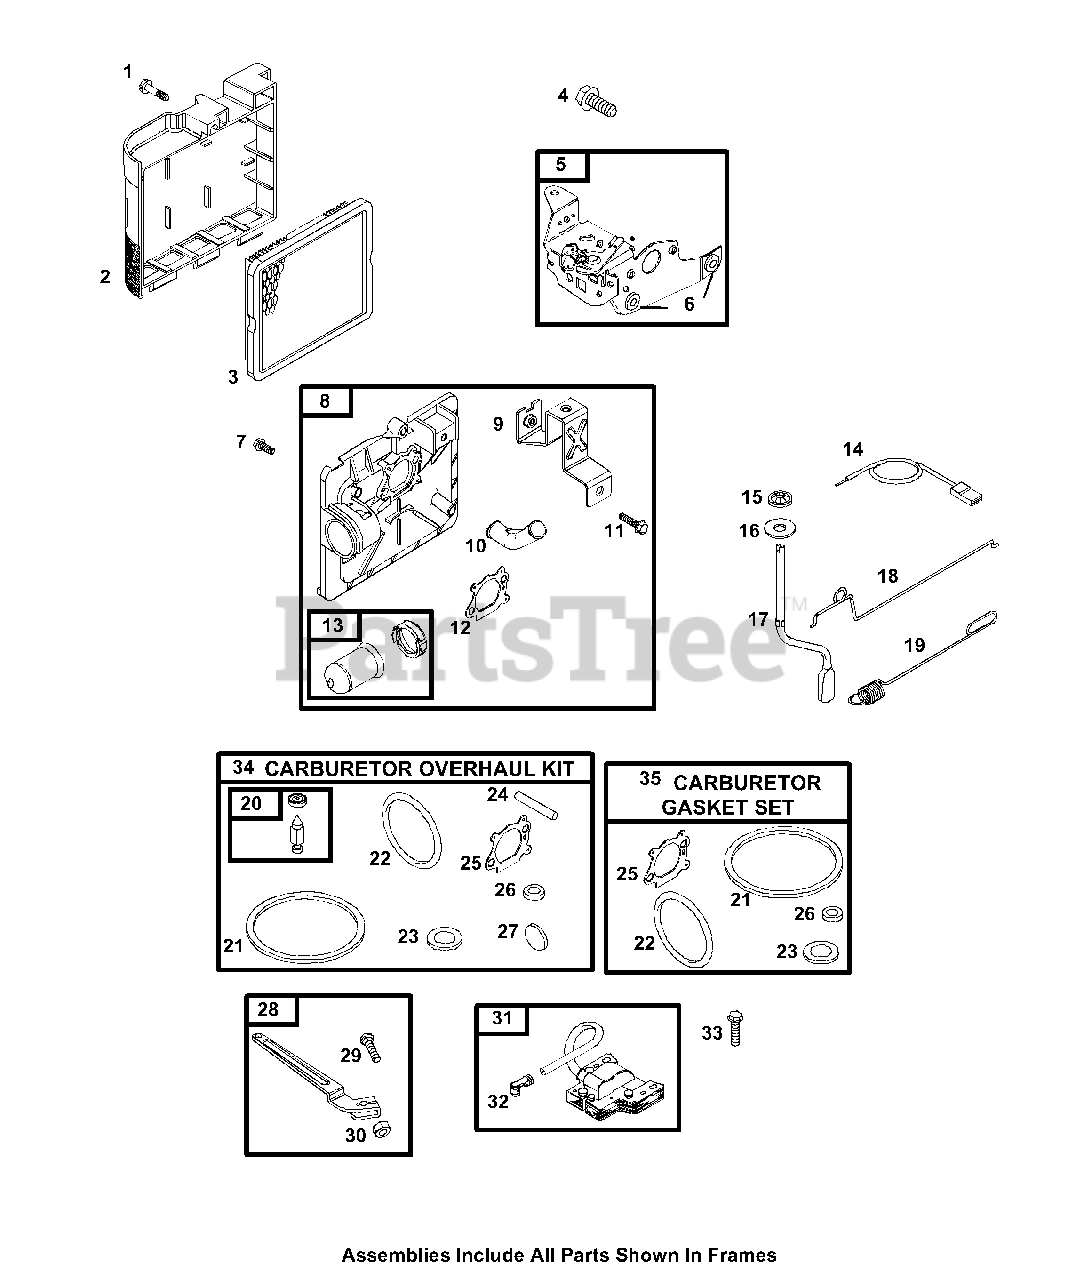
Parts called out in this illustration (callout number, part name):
1	Screw (Air Cleaner Cover)
2	Air Cleaner Cover
3	A/C Cartridge Filter
4	Screw (Control Bracket)
5	Control Bracket
6	Spacer
7	Screw (A/C Primer Base)
8	A/C Primer Base
9	Air Cleaner Primer Bracket
11	Screw (Support Bracket)
12	Air Cleaner Gasket
13	Carburetor Primer
15	Retainer Governor Shaft
16	Washer (Governor Crank)
17	Governor Crank
18	Mechanical Governor Link
19	Governor Spring
20	Needle/Seat Kit
21	Float Bowl Gasket
22	O-Ring Seal (Intake Manifold)
23	Sealing Washer
24	Float Hinge Plug
25	Air Cleaner Gasket
26	Choke/Throttle Shaft Seal
28	Governor Control Lever
29	Bolt (Governor Control Lever)
30	Nut (Governor Control Lever)
31	Magneto Armature
32	Sparkplug Terminal
33	Screw (Magneto Armature)
34	Carburetor Overhaul Kit
35	Carburetor Gasket Set
